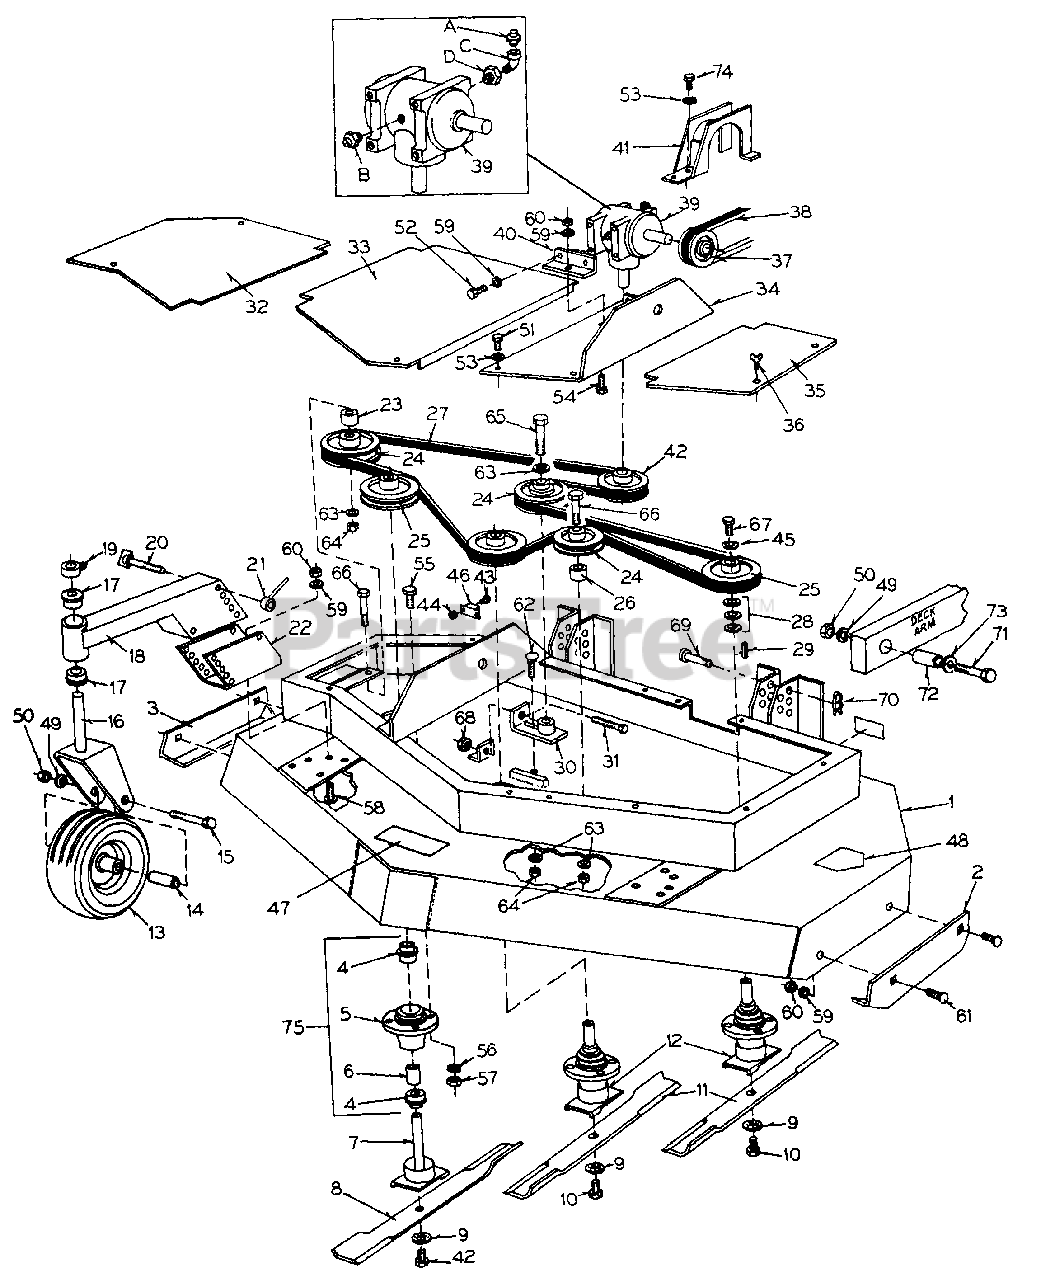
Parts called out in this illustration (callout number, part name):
1	Rear Discharge Deck, 52"
4	Spindle Bearing, 7/8"
5	Spindle Housing
6	Spindle Spacer
7	Spindle Shaft, LH Rotation
8	Blade, LH Rotation
10	Hex Bolt, 3/8-24 x 1 1/4", GR5
11	Blade, RH Rotation
12	Spindle Shaft, 7/8"
13	Gauge Wheel Assembly
14	Axle
15	Hex Bolt, 1/2-13 x 6 1/2", GR2
16	Gauge Wheel Fork
17	Drive Wheel Bearing, 1"
18	Gauge Wheel Mount
19	Set Collar, 1"
20	Wing Bolt, 3/8-16 x 4 1/2"
21	Handle Nut, 3/8-16
22	Gauge Wheel Mount Bracket
23	Idler Pulley Spacer
24	Idler Pulley, 3/8" ID x 5" OD
25	Spindle Pulley, 7/8" ID x 4 1/2" OD
26	Idler Pulley Spacer
27	Deck Belt, BB129
29	Key, 3/16" x 3/16" x 1"
30	Belt Tightener
31	Hex Tap Bolt, 1/4-20 x 4"
36	Thumb Screw, 1/4-20 x 1/2"
37	Gearbox Pulley, 3/4 ID x 4 1/2 OD
38	Deck Drive Belt, B52
39	Gearbox Assembly
40	Gearbox Mount Angle
42	Hex Bolt, 3/8-24 x 1 1/4", GR5, LH
44	Integral Star Washer Nut, No. 10-32
45	Spindle Washer
46	10 Amp Circuit Breaker
47	Decal, Caution - Whirling Blade
67	Hex Capscrew, 5/16-24 x 3/4", GR5
69	Clevis Pin, 1/2" x 1 1/2"
70	Hairpin Cotter, .120 x 2 1/4"
72	Deck Lift Arm Bushing
75	Spindle Housing Assembly
B	Grease Zerk, 1/4" NPT
C	Street Elbow, 1/8" x 90°
